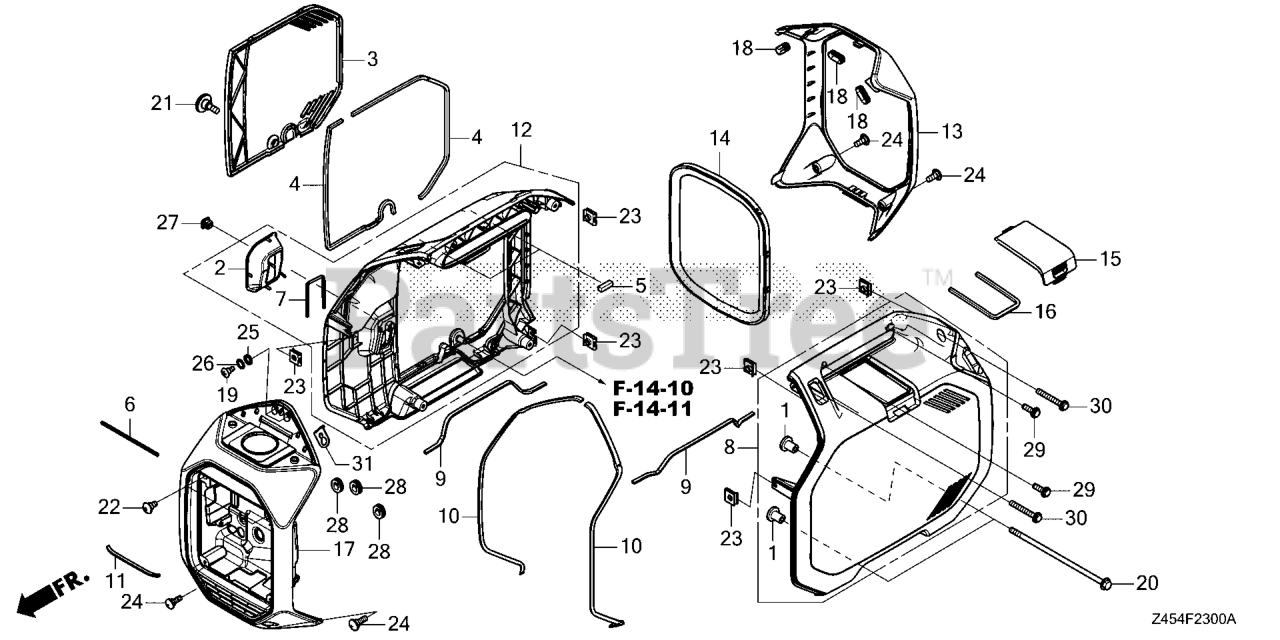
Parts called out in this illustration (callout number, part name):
1	COLLAR, FAN COVER
2	PROTR, STARTER ROPE
3	PANEL *NHC39R*
4	SEAL, MAINTE PANEL
5	SEAL A, L. PANEL
6	SEAL C, FR. PANEL
7	SEAL B, L. PANEL
8	PANEL COMP *NHC39R*
9	SEAL, SIDE PANEL
10	SEAL A, FR. PANEL
11	SEAL B, FR. PANEL
12	PANEL, L. *NHC39R*
13	COVER, RR. *R280*
14	SEAL RUB, RR. PANEL
15	LID COMP *NHC39R*
16	SEAL, PLUG CHECK LID
17	PANEL COMP *R280*
18	GROMMET A, SIDE COVER
19	SPL SCREW, PAN (5MM)
20	BOLT, FLANGE (6X164)
21	SCREW, SPECIAL (6X16)
22	SCREW, TRUSS (6X15)
23	NUT, SPRING (6MM)
24	SCREW, SPECIAL (6X15)
25	WASHER (7X12)
26	WASHER, WAVE (7MM)
27	GROMMET, SCREW (6MM)
28	GROMMET, FR. PANEL
29	SCREW-WASHER (6X20)
30	SCREW-WASHER (6X45) (NOT AVAILABLE)
31	PLATE, TETHER STRING
